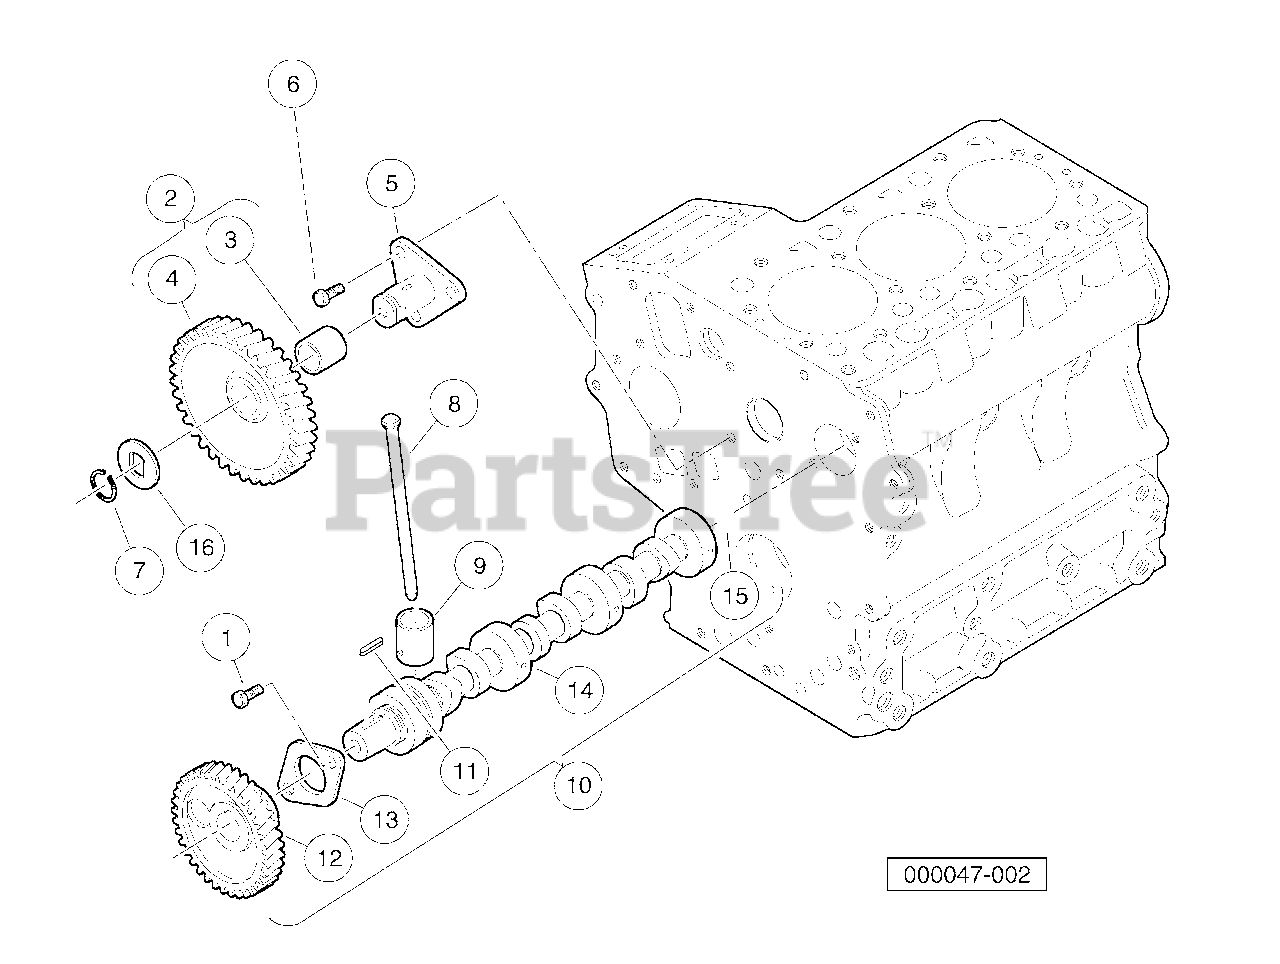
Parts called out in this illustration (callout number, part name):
1	Bolt, D722, Cam End
2	Gear, Idle
3	Bushing, D722 Idle Gear
4	Gear, Idle
5	Shaft, Idle Gear
6	Bolt, M6 X 1 X 14
7	Ring, Snap
10	Assy Camshaft, Long
11	Key, Feather, Long Camshaft
12	Gear, Cam.
13	Stopper, Camshaft
14	Camshaft
15	Ball, Check
16	Collar, Idle Gear
